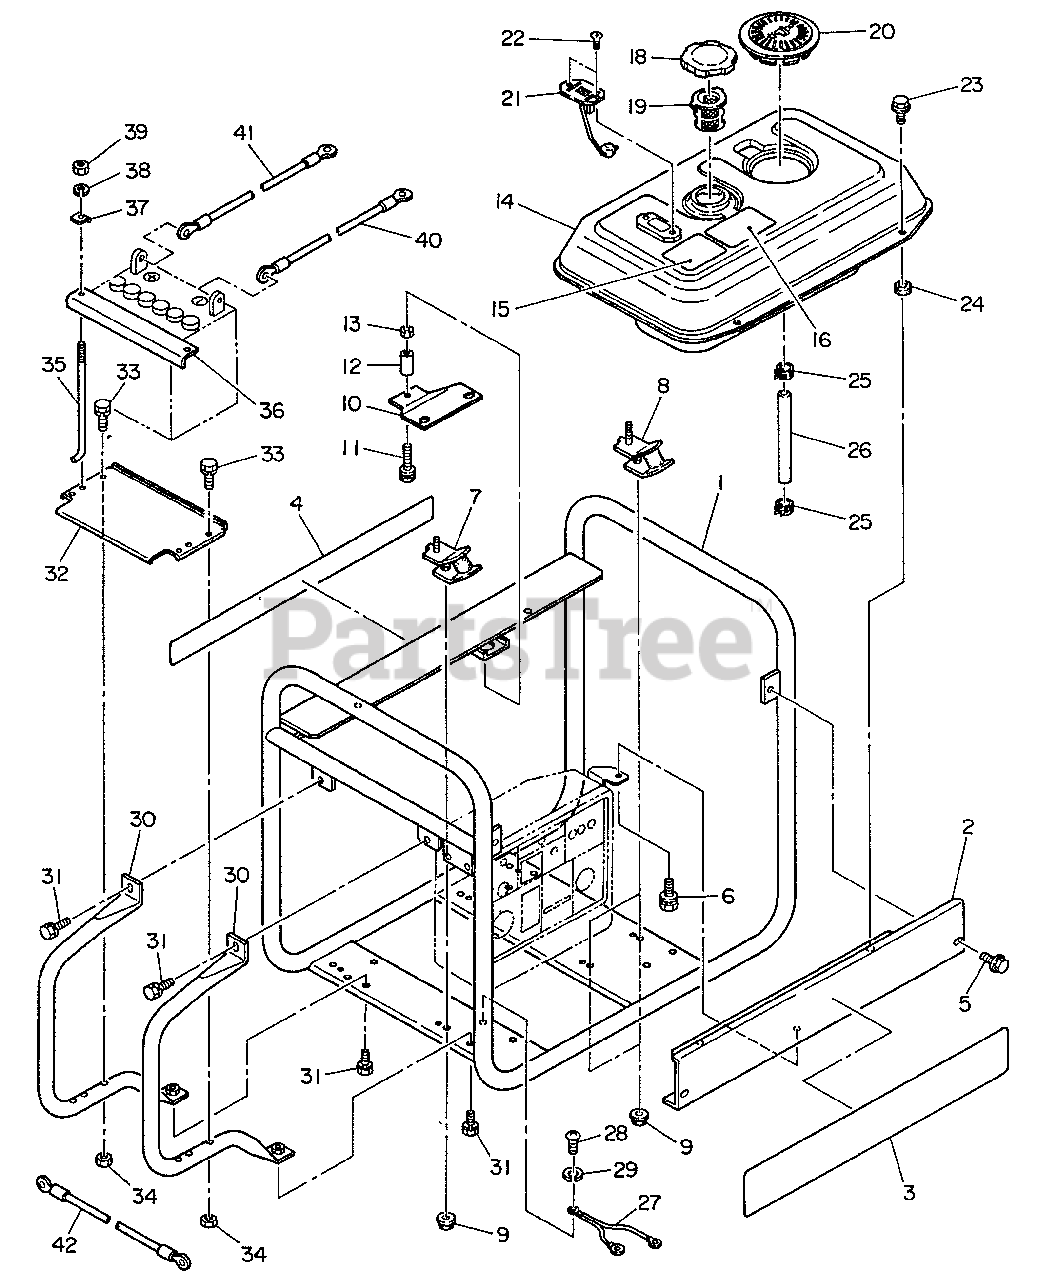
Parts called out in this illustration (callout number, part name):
1	PIPE FRAME, COMPL.
2	SIDE PLATE, COMPL.
3	LABEL - MODEL EG-5500E
4	LABEL - MODEL EG-5500E
5	BOLT - FLANGE
6	BOLT
7	MOUNT, RUBBER
8	MOUNT, RUBBER
9	NUT, FLANGE
10	STOPPER PLATE
11	BOLT
12	SPACER
13	NUT
14	FUEL TANK ASSY
15	LABEL - CAUTION -- OPERATION
16	LABEL - DANGER
19	FILTER, FUEL
20	PLUG COVER
21	FUEL GAUGE, COMPL.
22	SCREW
23	BOLT - FLANGE
24	RUBBER WASHER
25	CLAMP, HOSE
26	RUBBER PIPE (11.5×17.5×230 MM)
27	LEAD - GROUND
28	SCREW
29	WASHER, SPRING
30	BATTERY FRAME, COMPL.
31	BOLT
32	BATTERY BASE
33	BOLT ASSY
34	NUT
35	BATTERY BOLT
36	BATTERY RETAINER
37	BATTERY SUPPORT
38	LOCKWASHER
39	NUT
40	BATTERY CORD (-)
41	BATTERY CORD (+)
42	BATTERY CORD (+)
